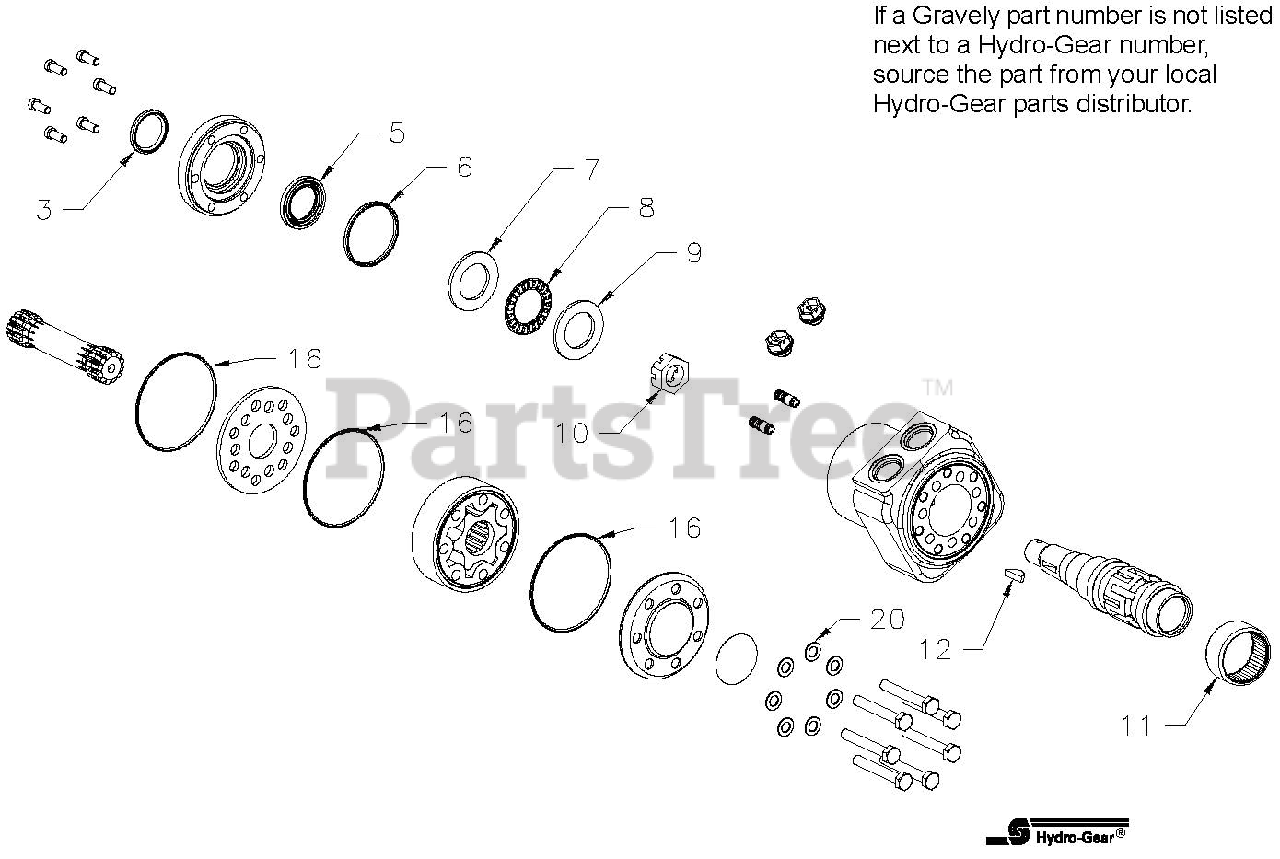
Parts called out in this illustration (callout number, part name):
10	Nut, Castle .75-20 Slotted Hex
12	Key, Woodruff .1875 x .75
NS	Seal Kit
NS	Kit, Axial Needle Bearing HGM P-Series
